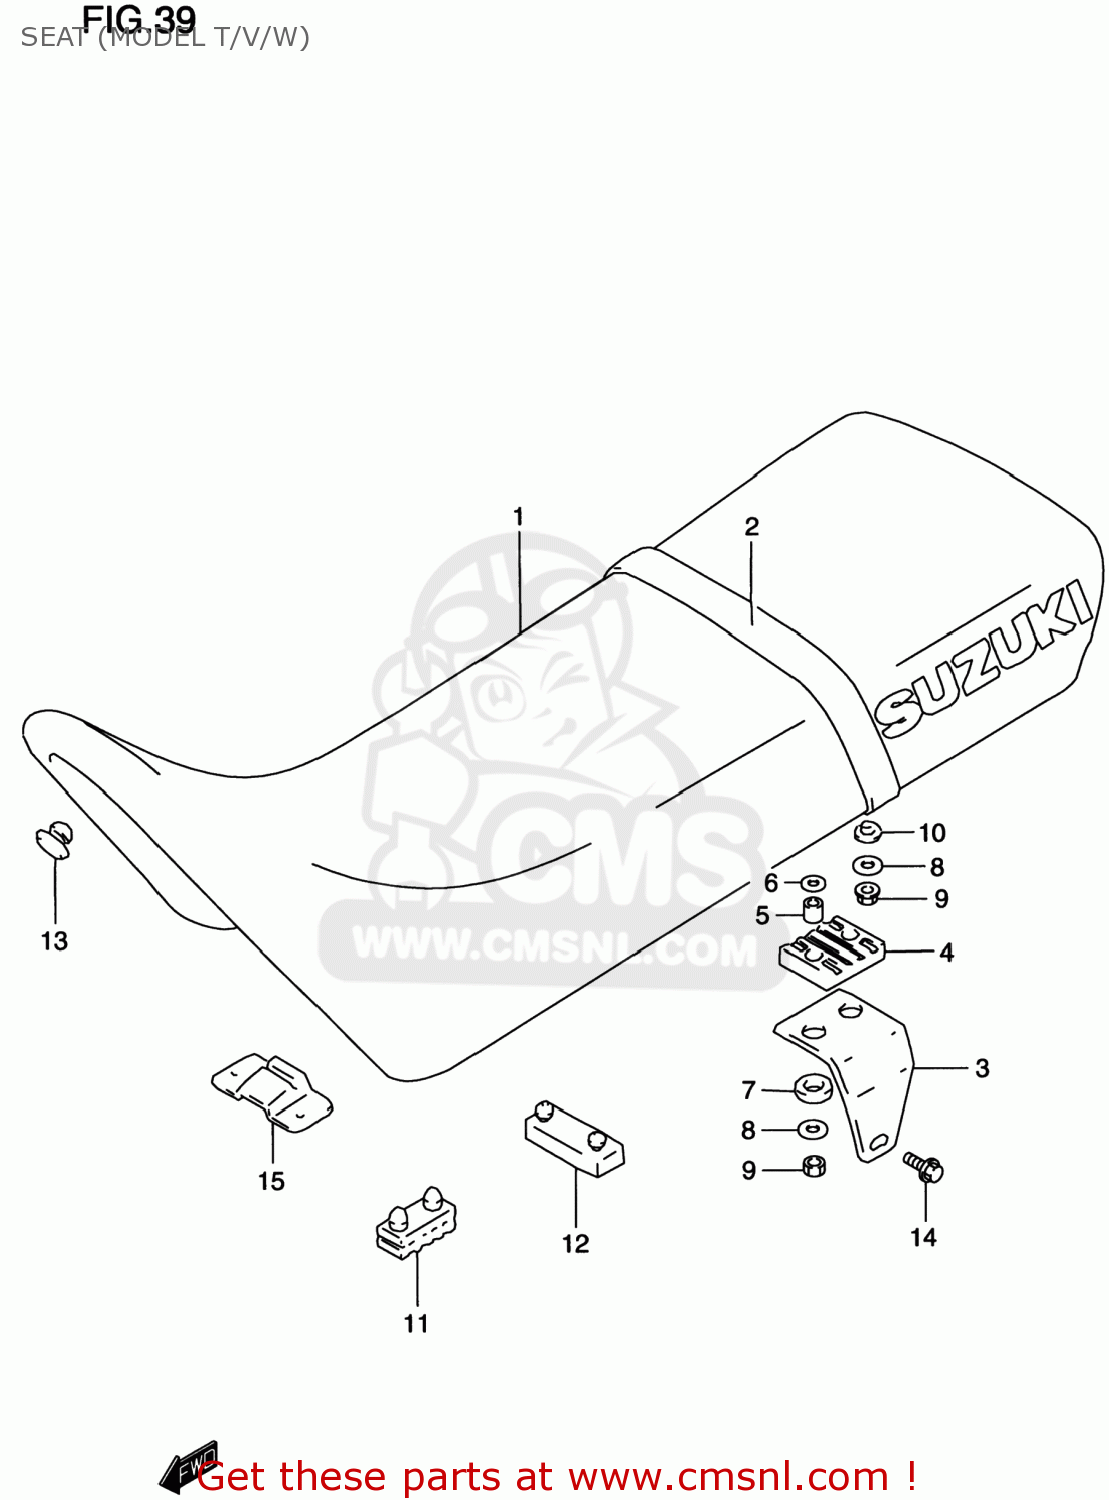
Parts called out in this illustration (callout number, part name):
1	SEAT SET
2	BAND,SEAT
3	BRACKET,SEAT
4	CUSHION,FR PLATE
5	SPACER,SEAT BRACKET
6	WASHER
7	CUSHION,SEAT FR
8	WASHER
9	NUT
10	WASHER
11	CUSHION,SEAT(40X20X15)
12	CUSHION,SEAT
13	CUSHION
14	BOLT
15	PLATE,SEAT FR HOOK
